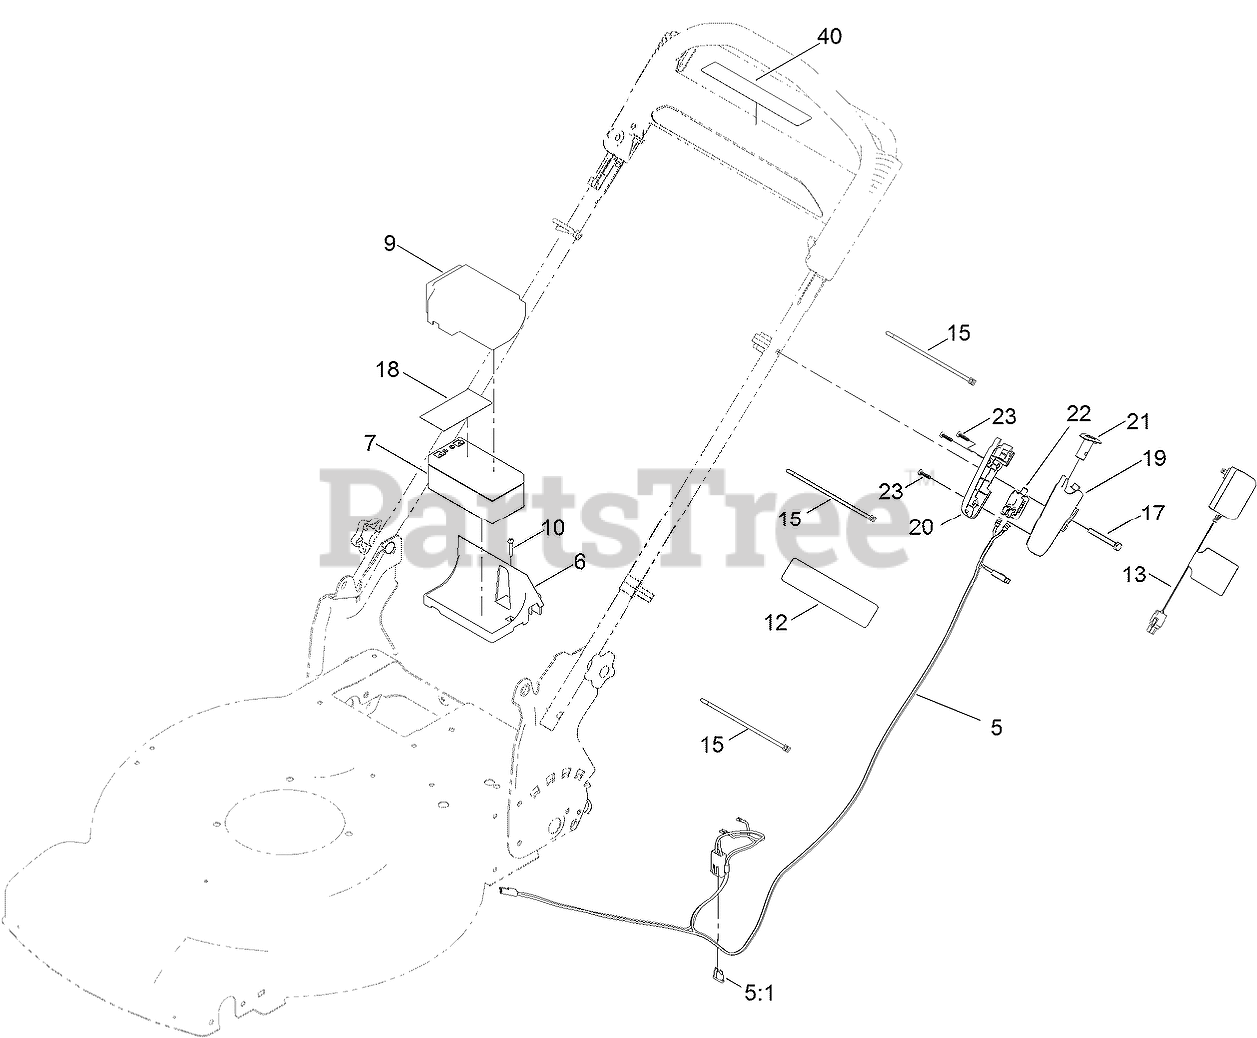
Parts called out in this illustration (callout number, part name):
5	HARNESS-WIRE
5:1	FUSE-40 AMP
6	TRAY-BATTERY
7	BATTERY-WET
9	COVER-BATTERY
10	SCREW-PPH, PLASTITE
12	DECAL-BATTERY CHARGING
13	CHARGER, BATTERY (12V)
15	TIE-CABLE
17	SCREW-HH
18	DECAL-TERMINAL, BATTERY
19	HOUSING-SWITCH, LH
20	HOUSING-SWITCH, RH
21	BUTTON-SWITCH
22	SWITCH-PUSH BUTTON
23	SCREW-PPH
40	DECAL-BUTTON, PUSH
